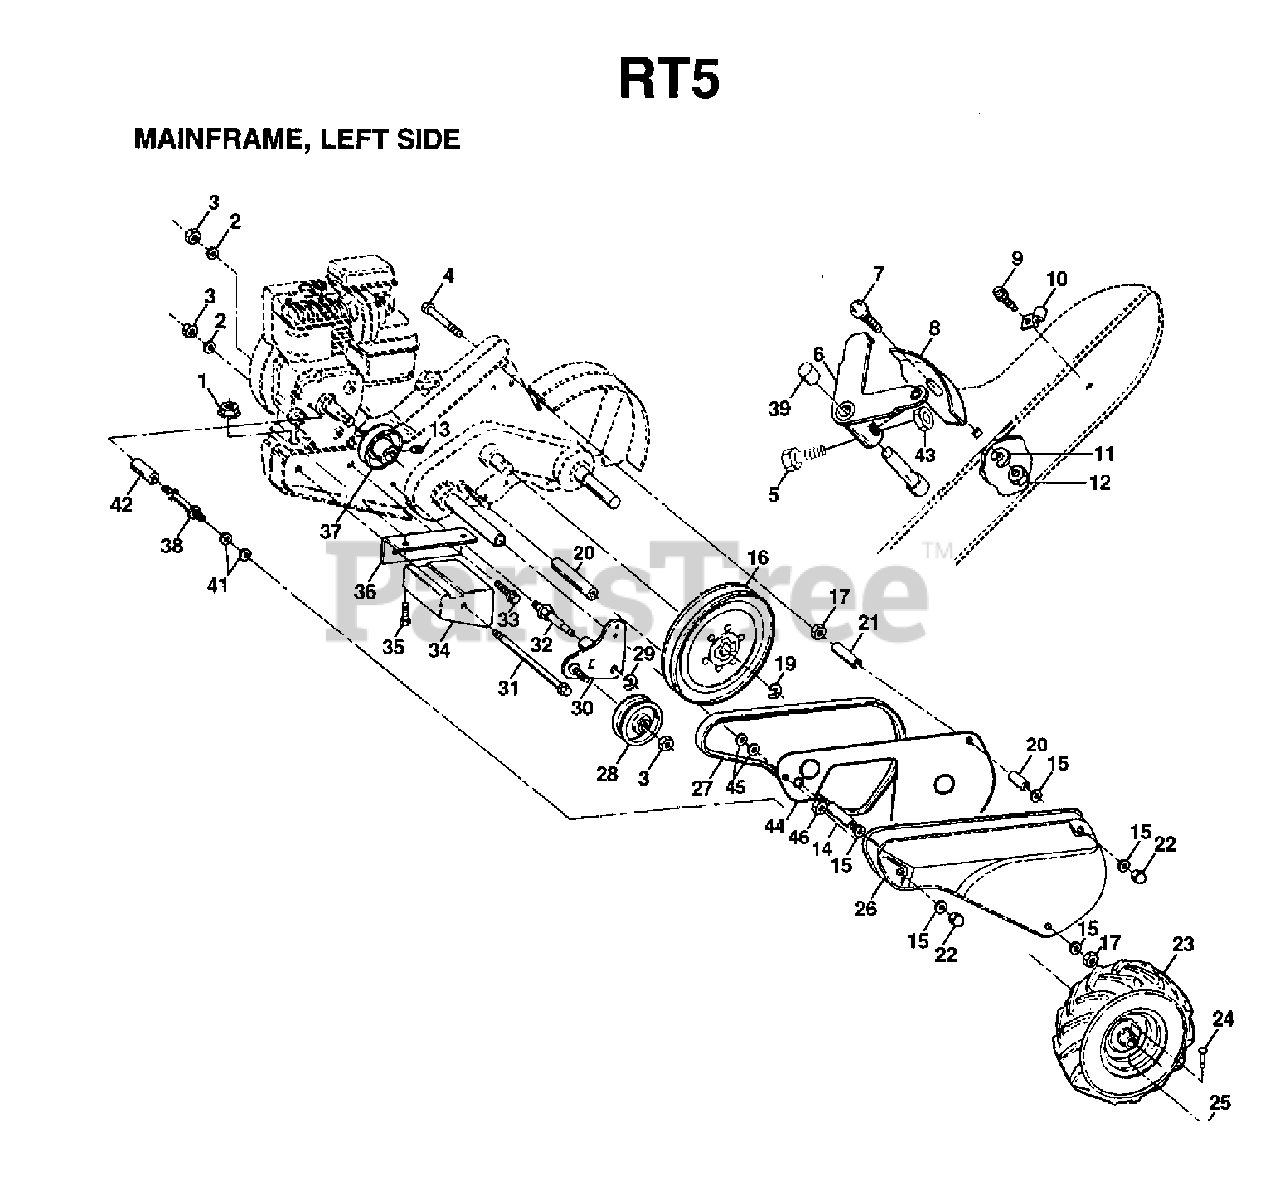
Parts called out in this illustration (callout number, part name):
1	NUT
2	WASHER, LOCK 3/8
3	NUT.HEX.3/8-16UNC
5	SCREW, SHIFT LEVER
6	LEVER ASM CRT
9	TAPPING SCREW
10	CONDUIT CLIP T
11	LOCKWASHER
12	NUT
13	SET SCREW **
15	WASHER
16	SHEAVE, TRANSMISSION
19	RETAINING RING LT
21	SPACER-SPLIT.327 X .42
24	RIVET,DRILLED
25	RETAINER M
27	V-BELT
28	PULLEY-IDLER TI
29	KLIP RING
30	BRACKET ASSY TI
31	BOLT.FIN.HEX.3/8-16UNC
32	SHIFT ARM CRT
33	BOLT
34	COUNTERWEIGHT.LH.CRT
36	BRACKET LH CRT
37	ENGINE PULLEY
38	BELT GUARD STUD
39	CAP.PLUNGER.BLACK
42	SPACER
45	WASHER LT
46	LOCKNUT
5321243-66	RIM
5321247-18	VALVE STEM LT
